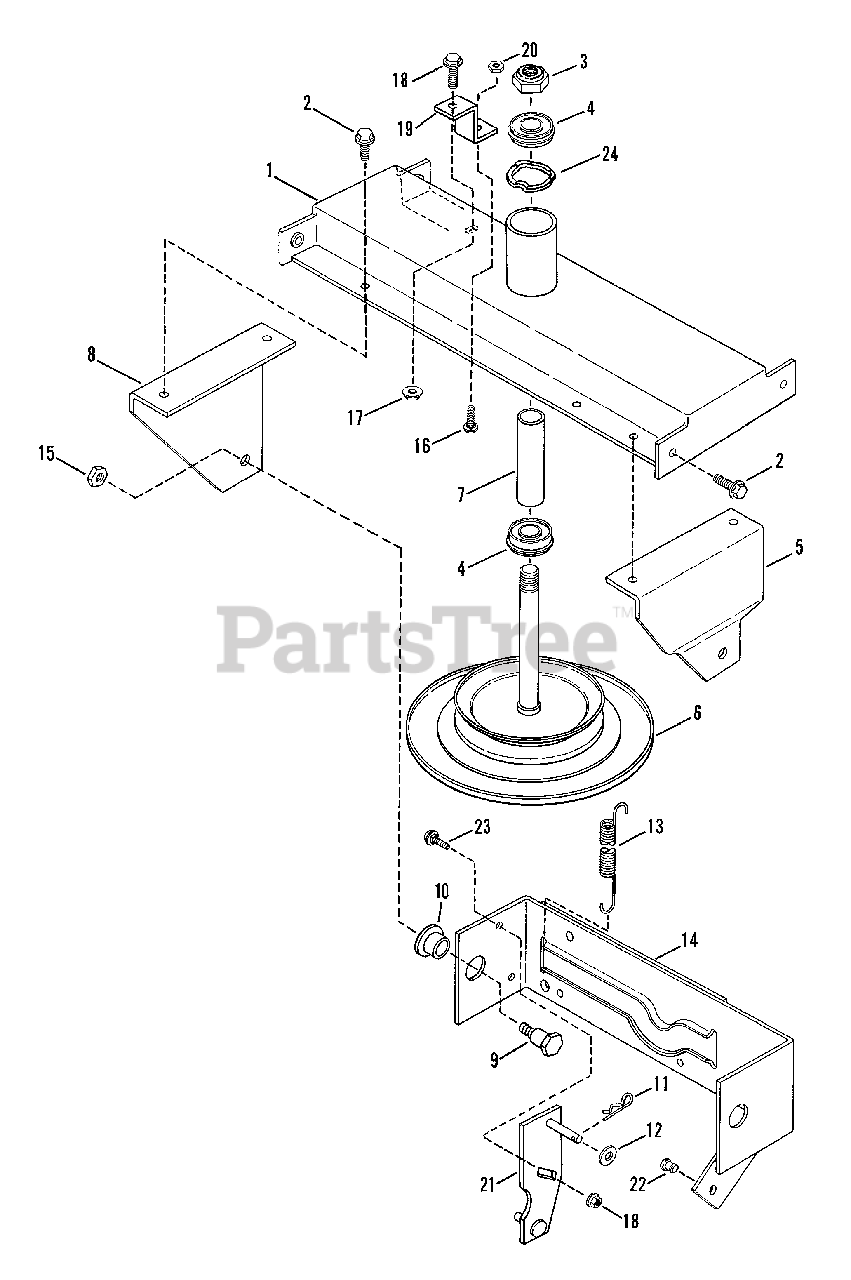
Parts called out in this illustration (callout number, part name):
1	SUPPORT ASSM'Y., Disc Drive
2	SCREW, 5/16-18 x 1/2" Self Tap
3	LOCKNUT, 5/8-18 Hex
4	BEARING
5	BRACKET, Yoke Pivot, L.H
6	DISC-DRIVE ASSM'Y.
8	BRACKET, Yoke Pivot, R.H.
9	BOLT, 5/16-18 x 1-5/16" Shoulder
10	BEARING, Yoke
11	PIN, Hair
12	WASHER, 5/16 Flat
13	SPRING
14	YOKE, Clutch
15	NUT, 5/16-18 Hex FL Lock
16	BOLT, 5/16-18 x 1-1/2" Carriage
17	NUT, 5/16-18 Hex Flange Lock
18	BOLT, 5/16-18 x 3/4" Hex Flange Lock
19	YOKE STOP ASSEMBLY
20	JAM-NUT, 5/16-18 Hex
21	ANCHOR, Spring
22	BEARING, Nyliner
23	BOLT, 5/16-18 x 3/4" Carriage
24	WASHER, Wave
